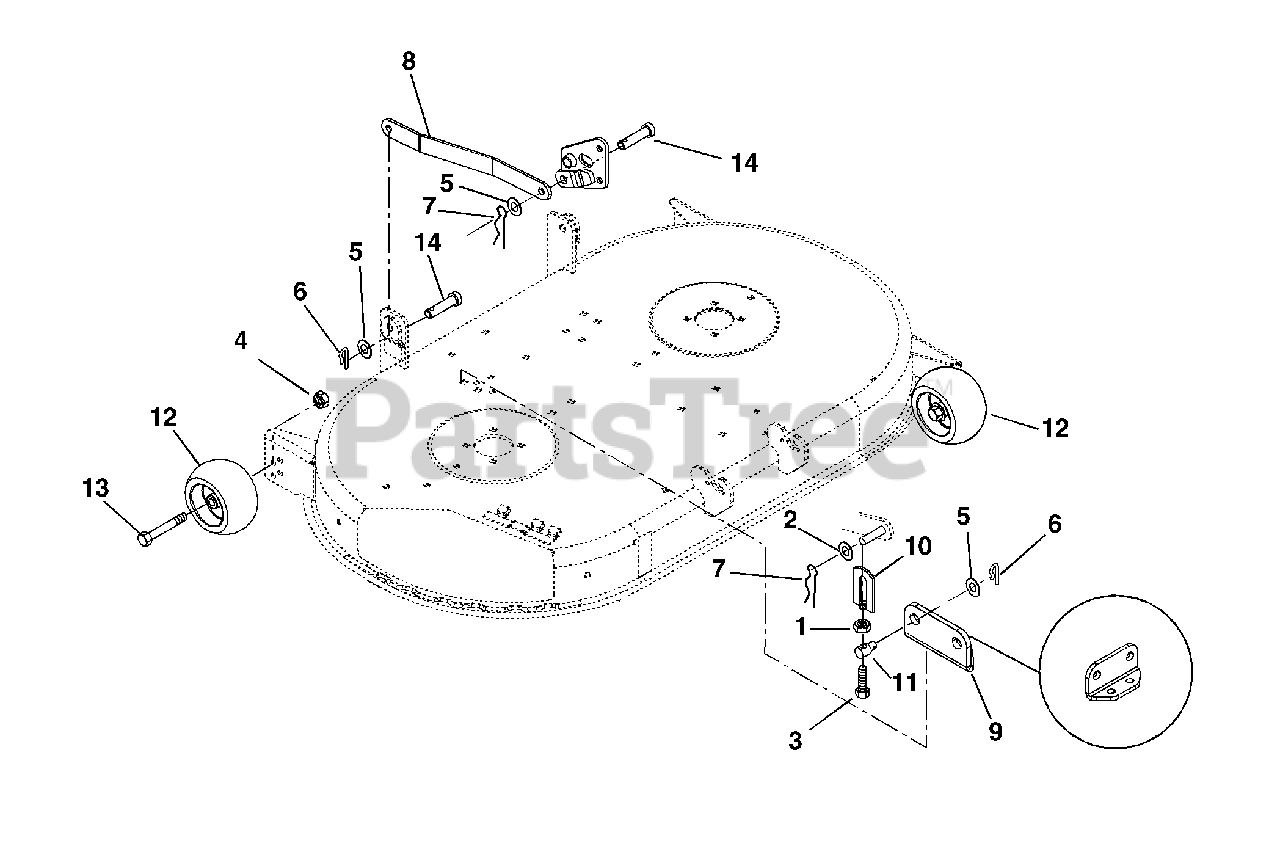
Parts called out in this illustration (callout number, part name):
1	@NUT-LK-CTR .38-16 YWZC
2	@WSHR-FL-STL.563X1.38X.109YWZC
3	BLT-HEX .38-16X2.50 FTH YWZC
4	@NUT-LK-TOP-FLG .38-16 YWZC
5	WSHR-FL-STL .505X.880X.072 YWZ
6	CLIP, SPRING
7	PIN-HAIR-EXT .12X.31X2.37 YWZC
8	LINK, LIFT (SIERRA)
9	BRACKET, LIFT
10	WELDMENT, ADJUSTMENT LINK
11	TRUNNION
12	WHEEL 5 X 3
13	BLT-SHLDR .38-16X2.50 HWH G5
14	PIN-CLEV .50X1.00 YWZC
